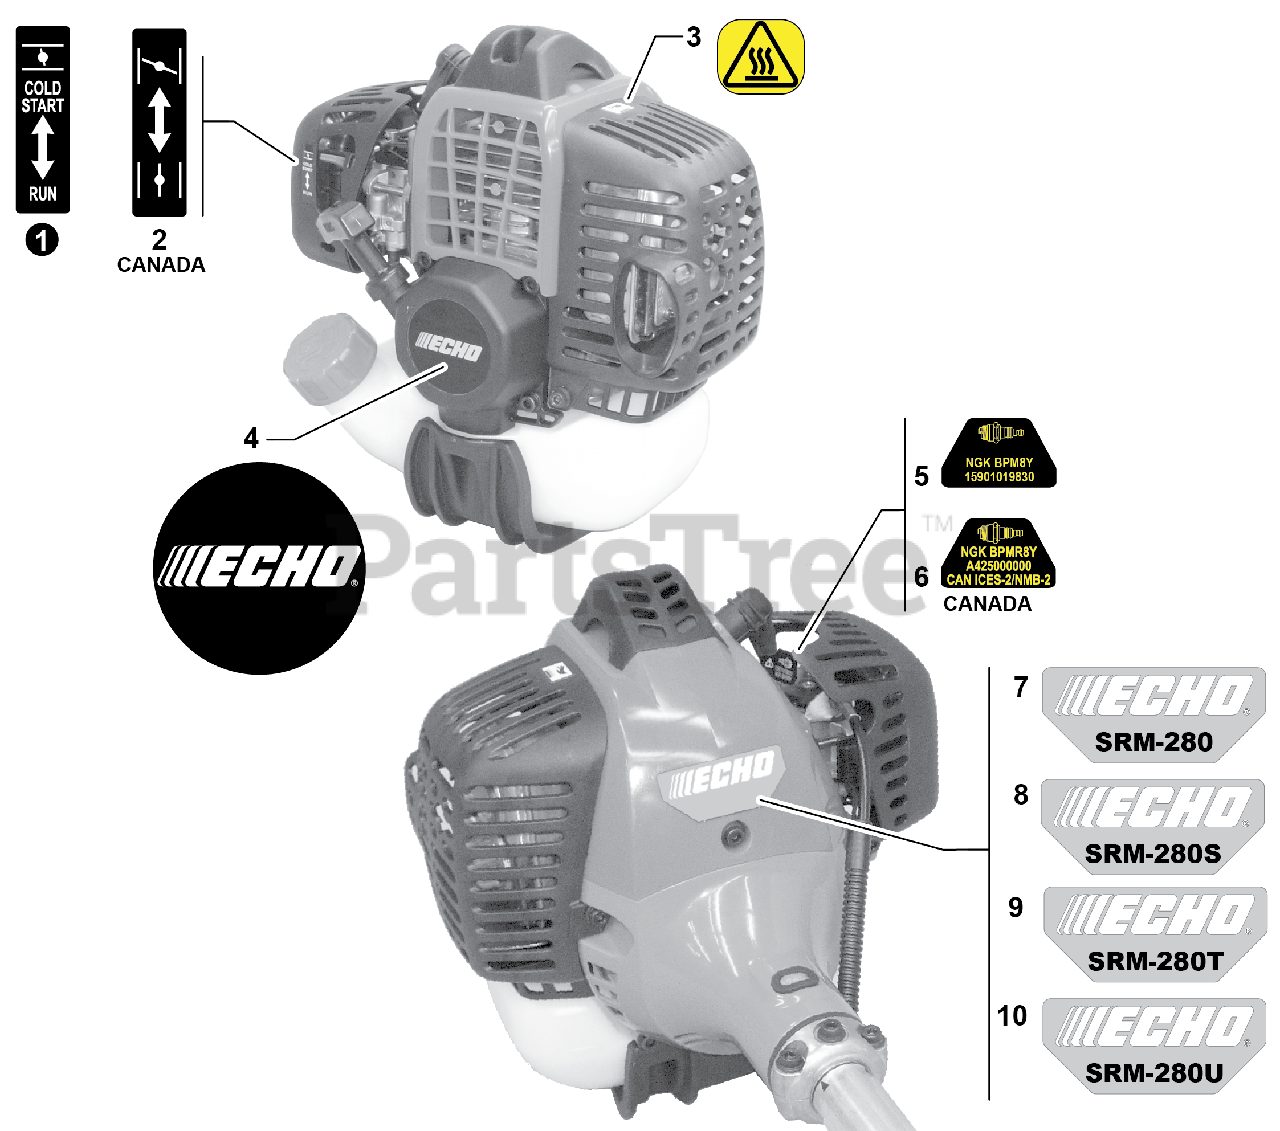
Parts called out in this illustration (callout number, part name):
1	LABEL, CHOKE
2	LABEL, CHOKE
3	LABEL, CAUTION - HOT
4	LABEL, RECOIL STARTER
5	LABEL, SPARK PLUG - BPM8Y
6	LABEL, SPARK PLUG - BPMR8Y
7	LABEL - MODEL SRM-280
8	LABEL - MODEL SRM-280S
9	LABEL - MODEL SRM-280T
10	LABEL - MODEL SRM-280U
